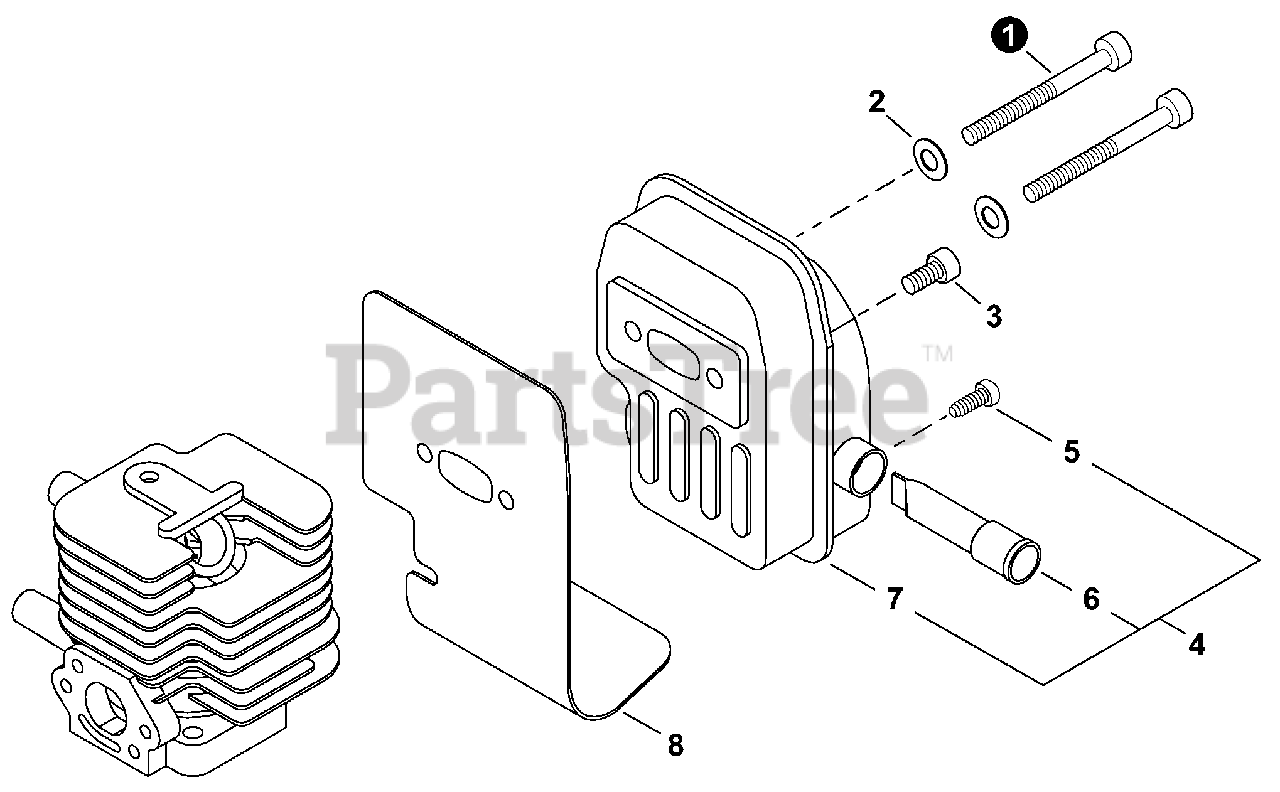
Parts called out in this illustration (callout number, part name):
1	BOLT M5×50
2	WASHER, FLAT 5.5×10×0.8
3	BOLT 5×12
4	MUFFLER ASSY
5	SCREW, TAPPING 3×6
6	SCREEN, SPARK ARRESTER
7	MUFFLER
8	HEAT SHIELD, EXHAUST
